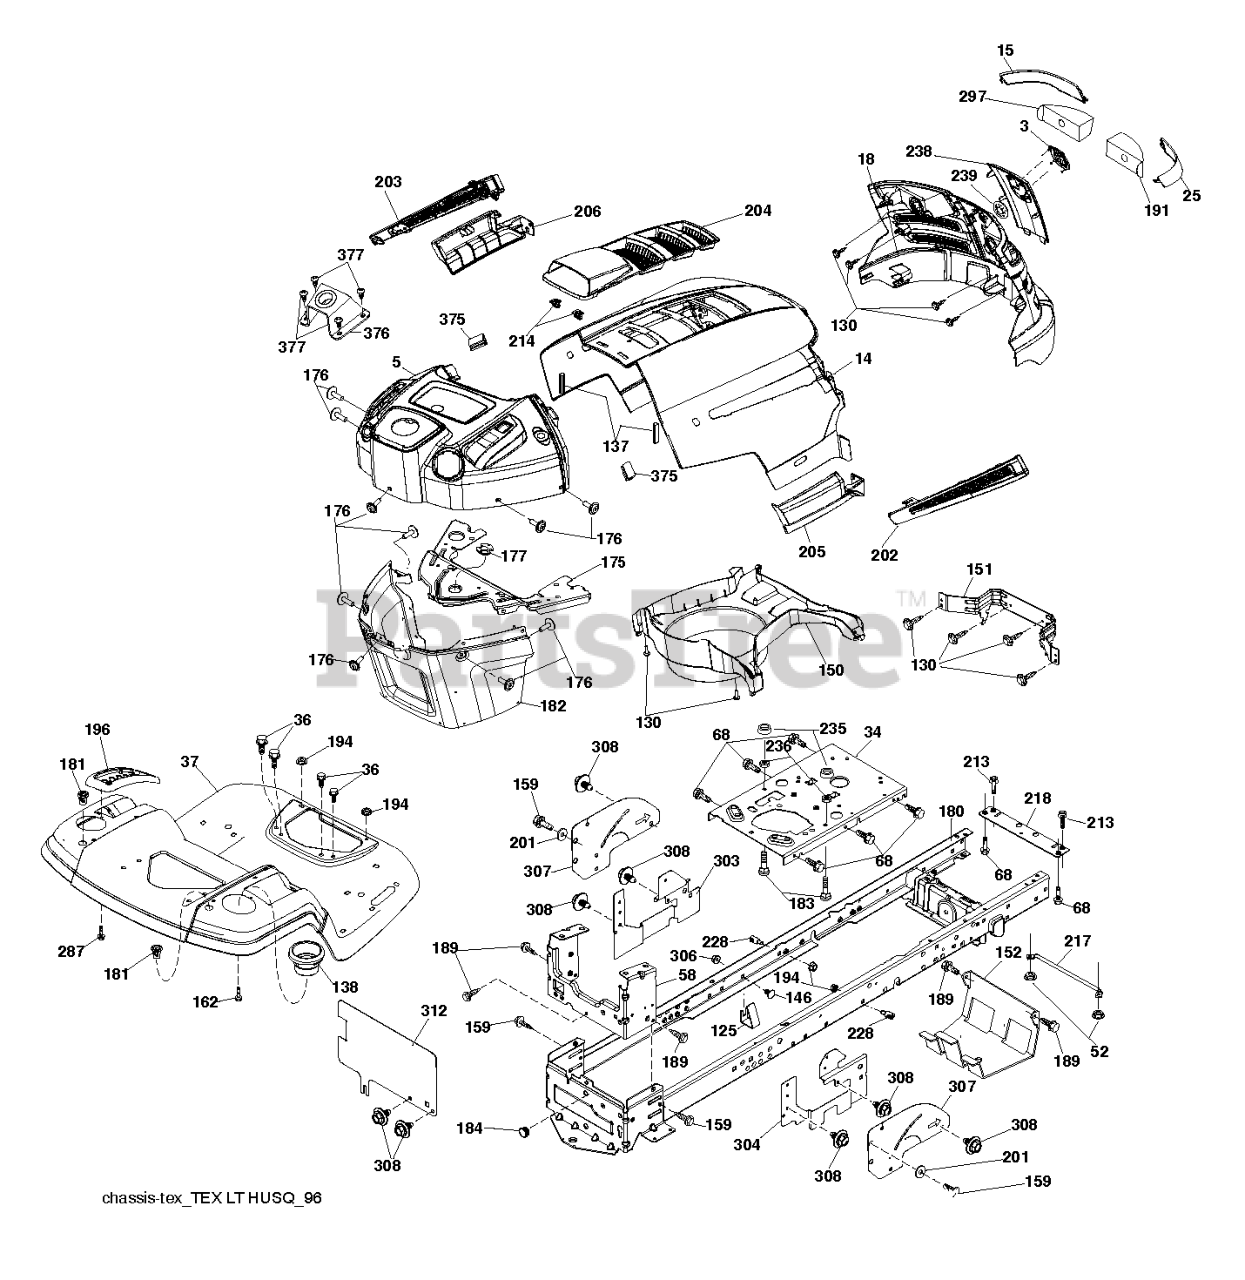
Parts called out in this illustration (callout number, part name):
3	LOGO.HUSQ.GT.LT.CROWN.H
5	DASH.UPPER.HUS.LT.CABLE.CLUTCH
14	HOOD.HUSQVARNA.LT.ORANGE
15	LENS.HUSQVARNA LT.RH
18	GRILLE.SVC.HUSQVARNA.GREY
25	LENS.HUSQVARNA LT.RH
34	PLATE.ENGINE.WELDED.CHASSIS
36	SCREW 5/16"
37	FENDER.TLT.PDL.CNTRL.W/CPH.ORG
52	LOCKNUT
58	DRAWBAR UPPER 2PC SMALL FENDER
68	SCR 5/16-18 X 1/2 SELFTAP ZN
125	CLIP.FUEL.LINE
130	SCREW.#10 X 0.750.BOS
137	BUMPER DASH
138	HOLDER.CUP.LT.GREY
146	BOLT.RDHD.SHT.SQNK.3/8-16X5/8
151	BRACKET PIVOT
152	SHIELD.BROWNING.W/TEX
159	SCREW, 3/8-16X3/4
162	SCREW.HI-LO.CONSOLE
175	CROSSMEMBER
176	SCREW.#10-24X5/8.RN.QU
177	BUSHING STEERING
180	CHASS.WLDMNT.TL.12GA/2P.48/54
181	BUSHING.MNT.FEND.CRGO.TEX.49
182	DASH.LOWER.PREDATOR LT
183	BOLT.5/16-18X1-1/4 FULL THD
184	PLUG.DEMO.625
189	SCREW
191	INSERT.REFLECTIVE.RH.
194	NUT LOCK HEX FLANGE 5/16-18
196	DECKLFT.CONSOL FULL ASSM GREY
201	WASHER
202	VENT.SIDE.HUSQVARNA.LT.RT
203	VENT.SIDE.HUSQVARNA.LT.LFT
204	SUBASM.TOP.VENT.HUSQ.LT
205	SKIRT.SIDE.HUSQVARNA.LT.RT
206	SKIRT.SIDE.HUSQVARNA.LT.LEFT
213	HCS 5/16C X 3/4
214	CLIP.RETAINER.TINNER.
217	ROD.PIVOT.HOOD
218	X-PIECE.HOOD.STOP.NON/
228	STUD.FASTNER.W/ANTI-ROTATE
235	SPACER FENDER
236	NUT.CENTERLOCK.5/16-
238	TRIM.HUSQ LT.668
287	SCREW 1/4X20
297	INSERT REFLECTIVE
303	SHIELD.LWR.LH.LTGT.NON30
304	SHIELD.LWR.RH.LTGT.NON30.NOTCH
306	NUT LOCK FLG 3/8-16 UNC
307	SHIELD.UPPER.LT.GT.ISO
308	BOLT.5/16-18UNCX3/4 W/SEMS.BLK
312	COVER DRBAR.LT.FRTTANK.ISO X43
375	BUMPER CLIP-ON. DASH 1"
376	MOUNT.ASM.HUSLT.UPPER.STRNG
377	SCREW 10 X 1/2 ZN PL PHIL PAN
